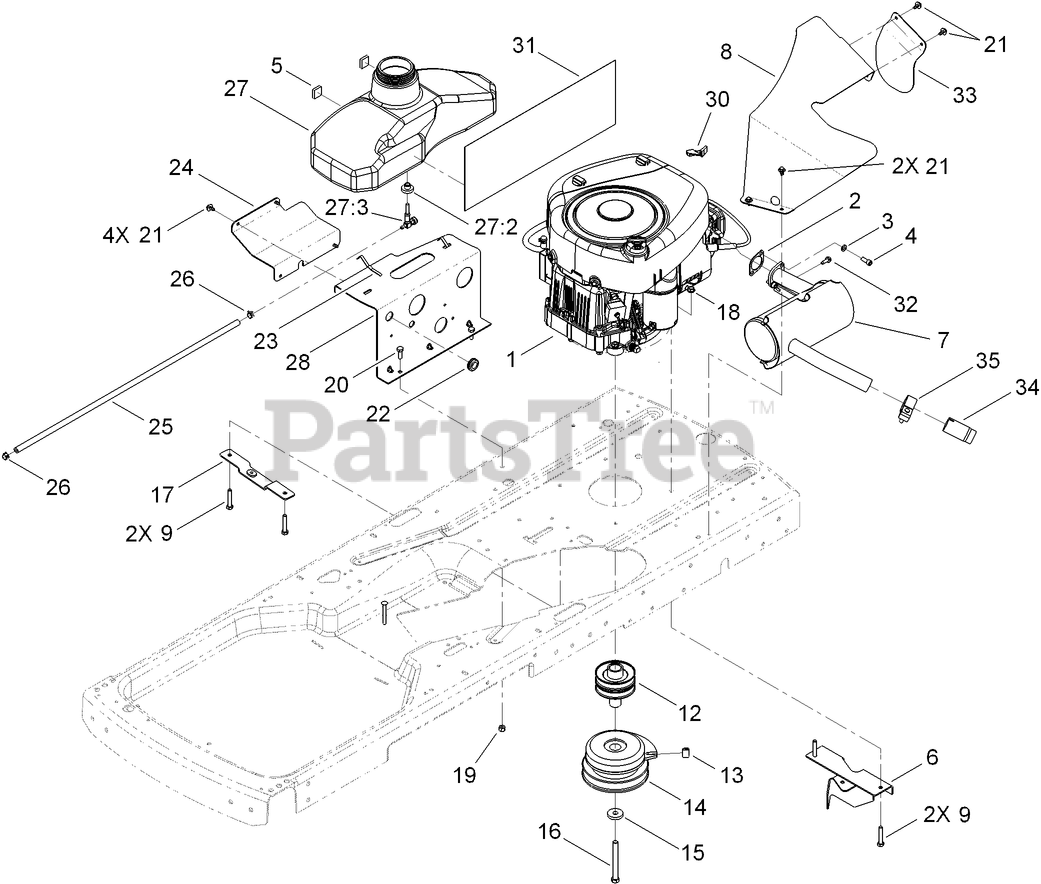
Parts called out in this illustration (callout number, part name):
2	GASKET-EXHAUST
3	WASHER-LOCK
4	SCREW-HSH
5	FOAM-SWITCH, SEAT
6	BRACKET-PIVOT
7	MUFFLER
8	SHIELD-CLIPPING
9	SCREW-HH
12	PULLEY-ENGINE
13	BUMPER
14	CLUTCH-ELECTRIC
15	WASHER
16	SCREW-HH
17	PLATE-MOUNT, IDLER
18	NUT-HF
19	NUT-LOCK, NI
20	SCREW-HH
21	SCREW-HHFTF
22	GROMMET
23	SPRING
24	PLATE-SUPPORT
25	HOSE-FUEL
26	CLAMP-HOSE
27	GAS TANK ASM
27:2	BUSHING
27:3	VALVE-FUEL
28	PLATE-TANK
30	REDUCER-THROTTLE, RPM
31	FOIL-SHIELD, HEAT
32	SCREW-HWH, THREAD ROLL
33	SHIELD-DEFLECTOR, HEAT
34	ARRESTER-SPARK
35	CLAMP-MUFFLER
